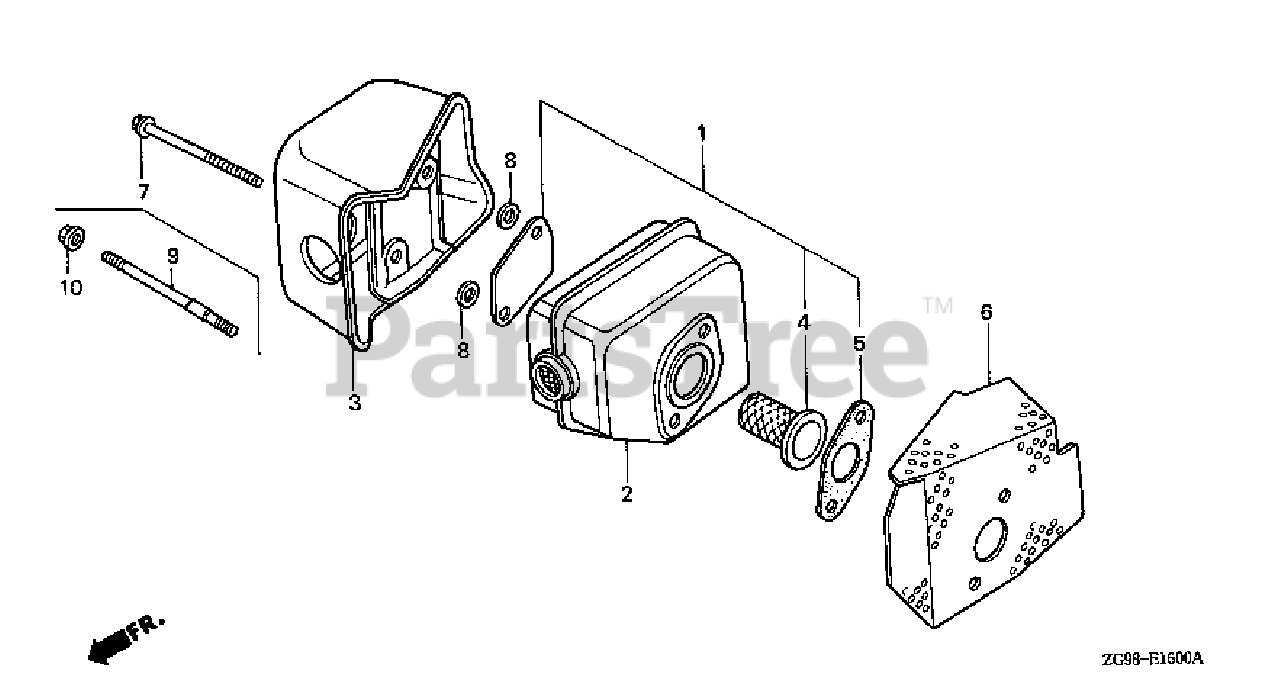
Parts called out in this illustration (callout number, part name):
1	ARRESTER KIT, SPARK
2	MUFFLER (FINLAND)
3	PROTECTOR, MUFFLER
4	ARRESTER KIT, SPARK
5	GASKET, MUFFLER
6	GASKET, MUFFLER
8	GASKET, PROTECTOR
9	BOLT, STUD (6X83)
10	NUT, SELF-LOCK (6MM)
